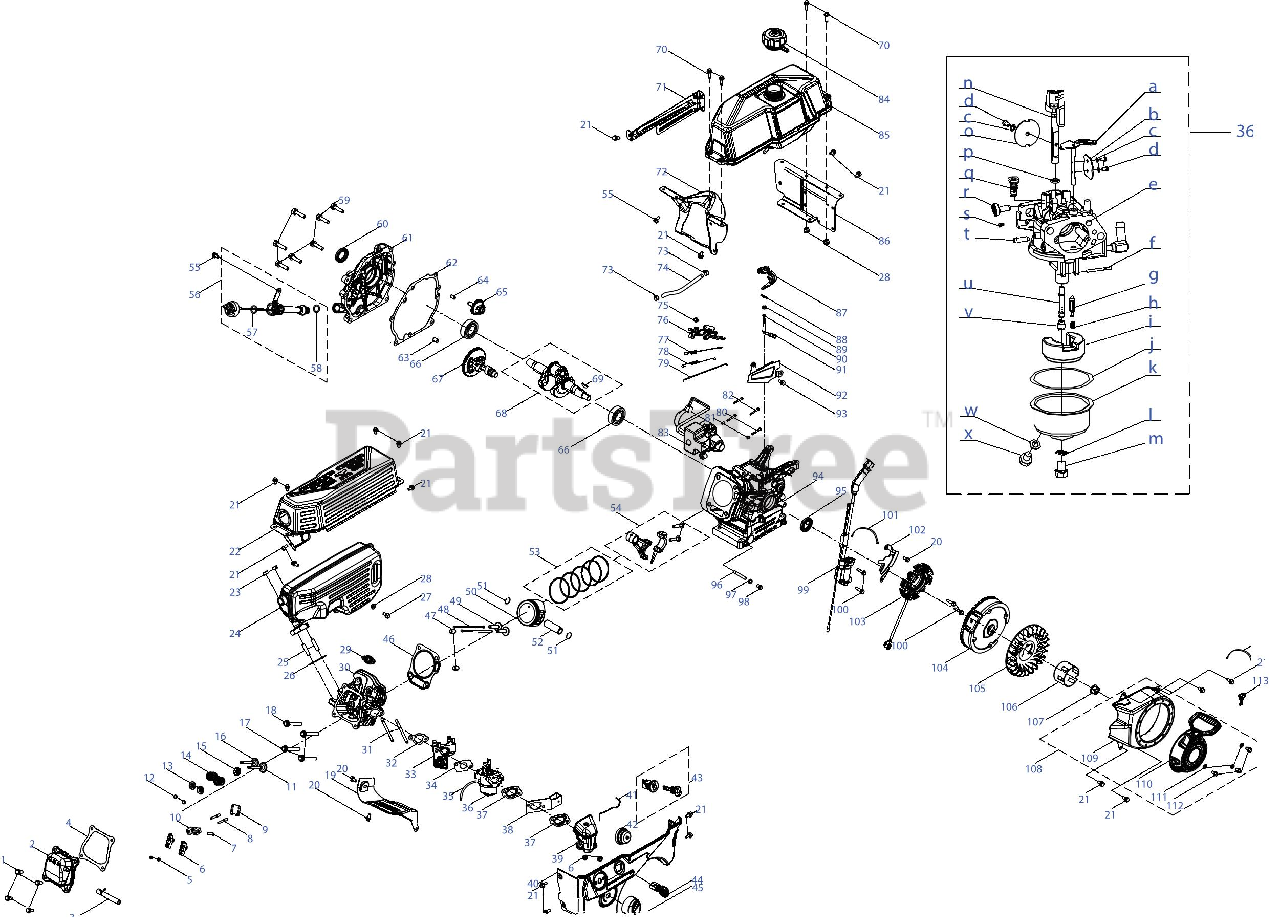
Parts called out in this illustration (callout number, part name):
1	Bolt, M6x16
2	Valve Cover
3	Breather Hose
4	Gasket, Valve Cover
5	Nut, M6
6	Rocker Arm Assembly
7	Rocker Arm Shaft
9	Rocker Arm Base
10	Rocker Arm Seat
11	Intake Vavle
12	Valve Adjust Cap, Exhaust
13	Valve Spring Seat
14	Valve Spring
15	Intake Valve Seal
16	Exhaust Valve
17	Bolt, M10x1.25x65
18	Bolt, M10x1.25x70
19	Shroud
20	Bolt, M6x12
21	Bolt, M6x12
22	Muffler Guard
23	Nut, M8
24	Muffler
25	Stud, M8x36
26	Gasket, Muffler
27	Bolt, M6x20
28	Nut, M6
29	Spark Plug
30	Cylinder Head
31	Stud, M6x92
32	Gasket, Carburetor Insulator
33	Insulator
34	Gasket, Carburetor
35	Fuel Hose, 3.2x6.5x150
36	Carburetor
37	Gasket, Air Filter
38	Choke Controller Assembly
39	Heater Box
40	Control Panel
41	Choke Linkage
43	Stop Switch
44	Throttle Lever Knob
45	Choke Lever
46	Gasket, Cylinder Head
47	Pin, 12x16
48	Push Rod
49	Tappet
50	Piston
51	Circlip
52	Piston Pin
53	Piston Ring Set
54	Connecting Rod Assembly
55	Bolt, M6x16
56	Dipstick
57	O-Ring, 21x2.77
58	O-Ring, 15.8x2.5
59	Bolt, M8x32
60	Oil Seal, 25x41.25x6
61	Crankcase Cover
62	Gasket, Crankcase
63	Pin, 9x14
64	Pin, 7x14
65	Governor Gear
66	Bearing, 6205
67	Camshaft
68	Crankshaft
69	Woodruff Key
70	Bolt, M6x22
71	Fuel Tank Insulator
72	Front Bracket, Fuel Tank
73	Clamp
74	Fuel Hose, 6.3x12.5x133
75	Bolt, M6x12
76	Governor Gear Bracket Assembly
77	Governor Spring
78	Idle Spring
79	Throttle Linkage
80	Bolt, M6x32
81	Pin, 8x8
82	Screw, M4x55
83	Electric Starter
84	Fuel Cap
85	Fuel Tank
86	Fuel Tank Base
87	Governor Lever
88	Cotter Pin
89	Oil Seal, 6x11x4
90	O-Ring, 5.2x1.9
91	Governor Gear Shaft
92	Choke Plate
93	Bolt, M6x10
94	Crankcase
95	Oil Seal, 25x41.25x6
96	Oil Drain Pipe
97	Washer, 10x1.5x16
98	Earth Bolt
99	Ignition Module
100	Bolt, M6x25
101	Tape, L=150mm
102	Lower Shield
103	Charging Coil
104	Flywheel
105	Cooling Fan
106	Starter Cup
107	Nut, M14x1.5
108	Recoil Starter
109	Blower Housing
110	Recoil Starter
111	Washer, 6
112	Bolt, M6x10
113	Stop Switch Key
